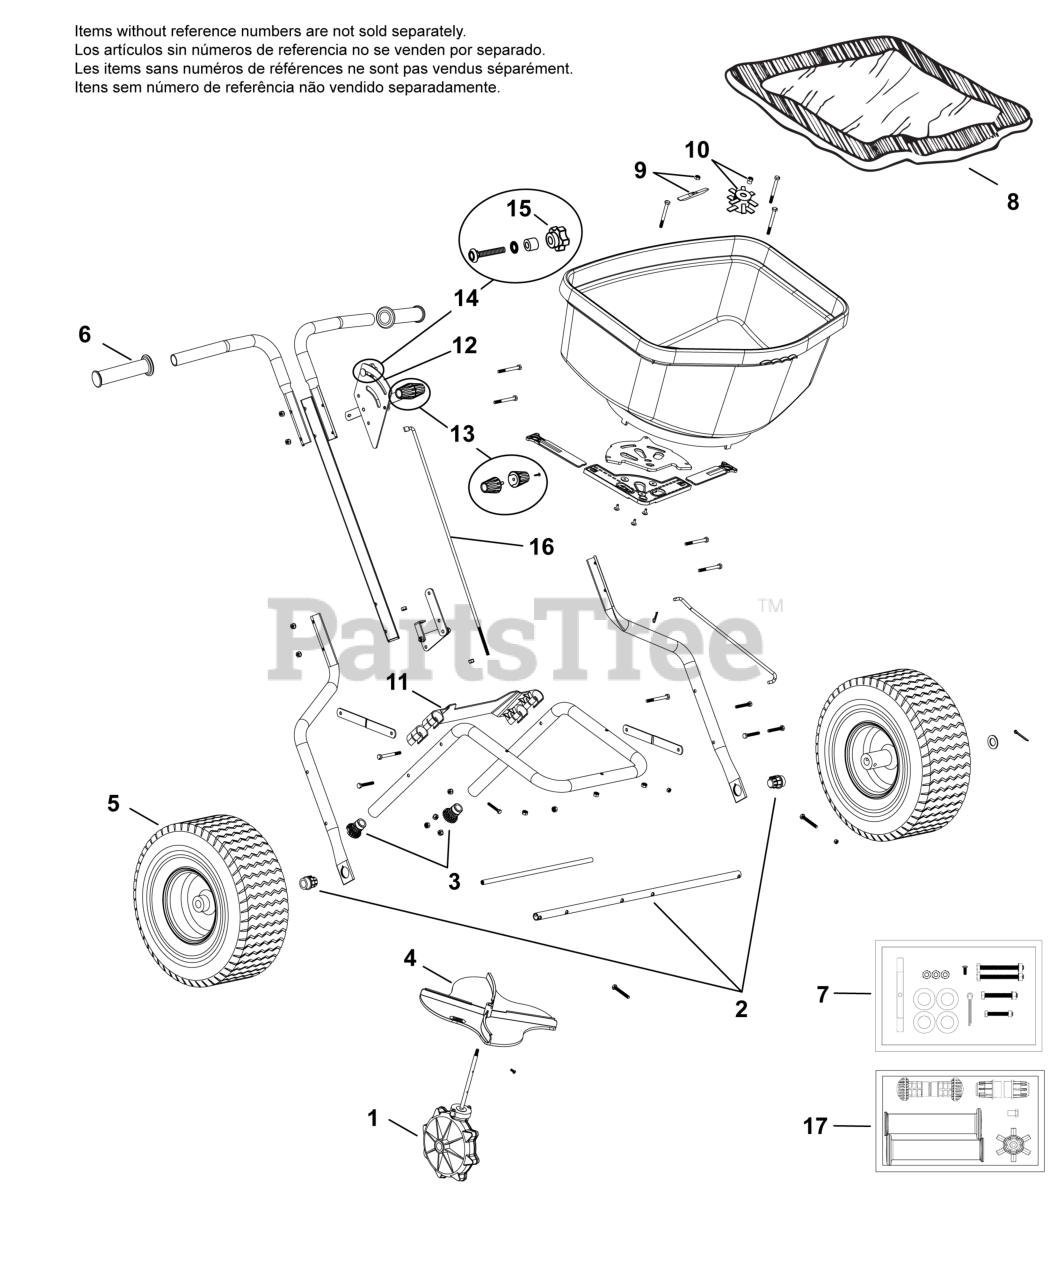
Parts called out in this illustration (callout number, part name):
1	GEAR BOX ASSEMBLY
2	DRIVE SHAFT W/2 BUSHINGS
3	GATE CONTROL ASSEMBLY, SS
4	IMPELLER & SECURING SCREW ASSEMBLY
5	RB-100 TIRE & RIM ASSEMBLY 14”
6	HANDLE GRIPS
7	HARDWARE BAG, SS
8	RAIN COVER
9	AUGER & LOCK NUT ASSEMBLY
10	REAR BAFFLE
